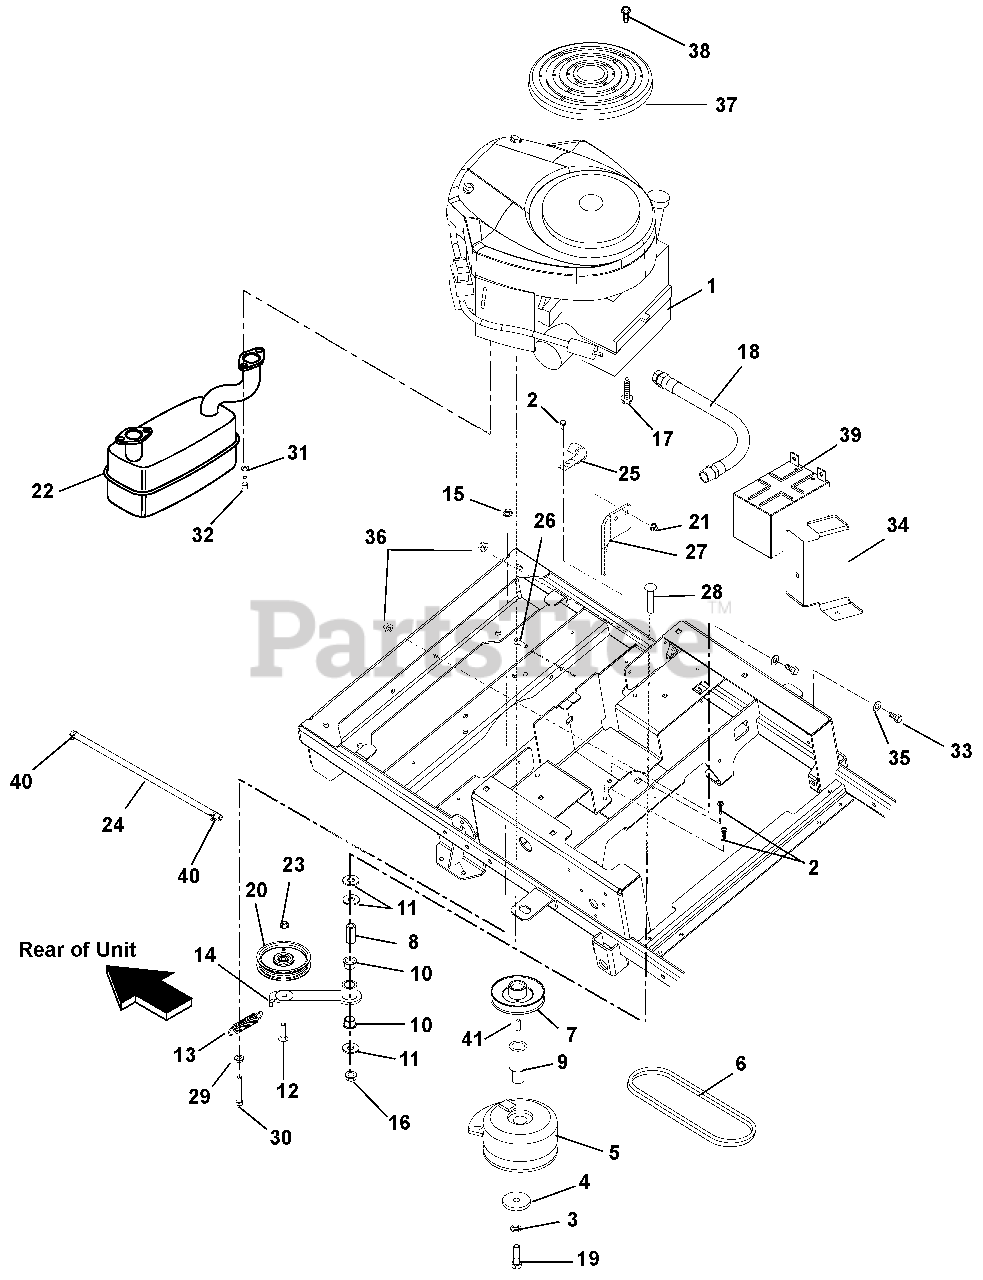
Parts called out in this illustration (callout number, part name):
1	Engine, 18HP V-Twin CE
2	Screw, Tapping .250-20 x .37 Hex Washer Head
3	Washer, Locking .44 x .109 Regular
4	Washer, Flat Steel .469 x 2.00 x .25
5	Clutch, XL
6	Belt, HA 62.50 Wrapped
7	Pulley, V 4.5 x 1.5 AB Section with Key
8	Bushing, Sleave .500 x .750 x .1.560
9	External, Crankshaft Lower
10	Bushing, Flange 0.75 x 0.875 x .625 x 1.125
11	Washer, Flat Steel .563 x 1.38 x .109
12	Bolt, Round Head Square Neck .38-16 x 1.50 Grade 5
13	Spring, Tension .105 x .812 x 3.88
14	Weldment, Ground Drive Idler Arm
15	Nut, 3/8-16 Flange Nyloc
16	Nut, Locking Top Flange .50-13
17	Screw, Tapping .38-16 x 1.00 Hex Washer Head
18	Hose Assembly, Oil Drive .38 x 11.5 OAL
19	Bolt, Hex .44-20 x 4.50 Grade 8
20	Assembly, 4" Idler
21	Nut, .31-18 Nyloc Flange
22	Muffler, Briggs & Stratton Twin
23	Nut, Locking Top Flange .38-16
24	Fuel Hose
26	Bolt, Hex .31-18 x 1.00 Grade 5
27	Clutch Stop
28	Bolt, Round Head Square Neck .50-13 x 2.50 Grade 5
29	Nut, Flange .375-16
30	Bolt, Hex .38-16 x 2.50 Grade 5
31	Washer, Locking .31 x .078 Regular
32	Screw, Cap .31-18 x .75
33	Bolt, Hex .25-20 x .75
34	Bracket, Battery Hold Down
35	Washer, Flat Steel .281 x .62 x .065
36	Nut, KEPS .250-20
37	Guard, Briggs & Stratton Engine
38	Screw, 8-16 x .87
39	Battery, 12V, 12A-190 CCA
40	Clamp, Fuel Line
41	Key, Straight .25 x 2.0 x .25
